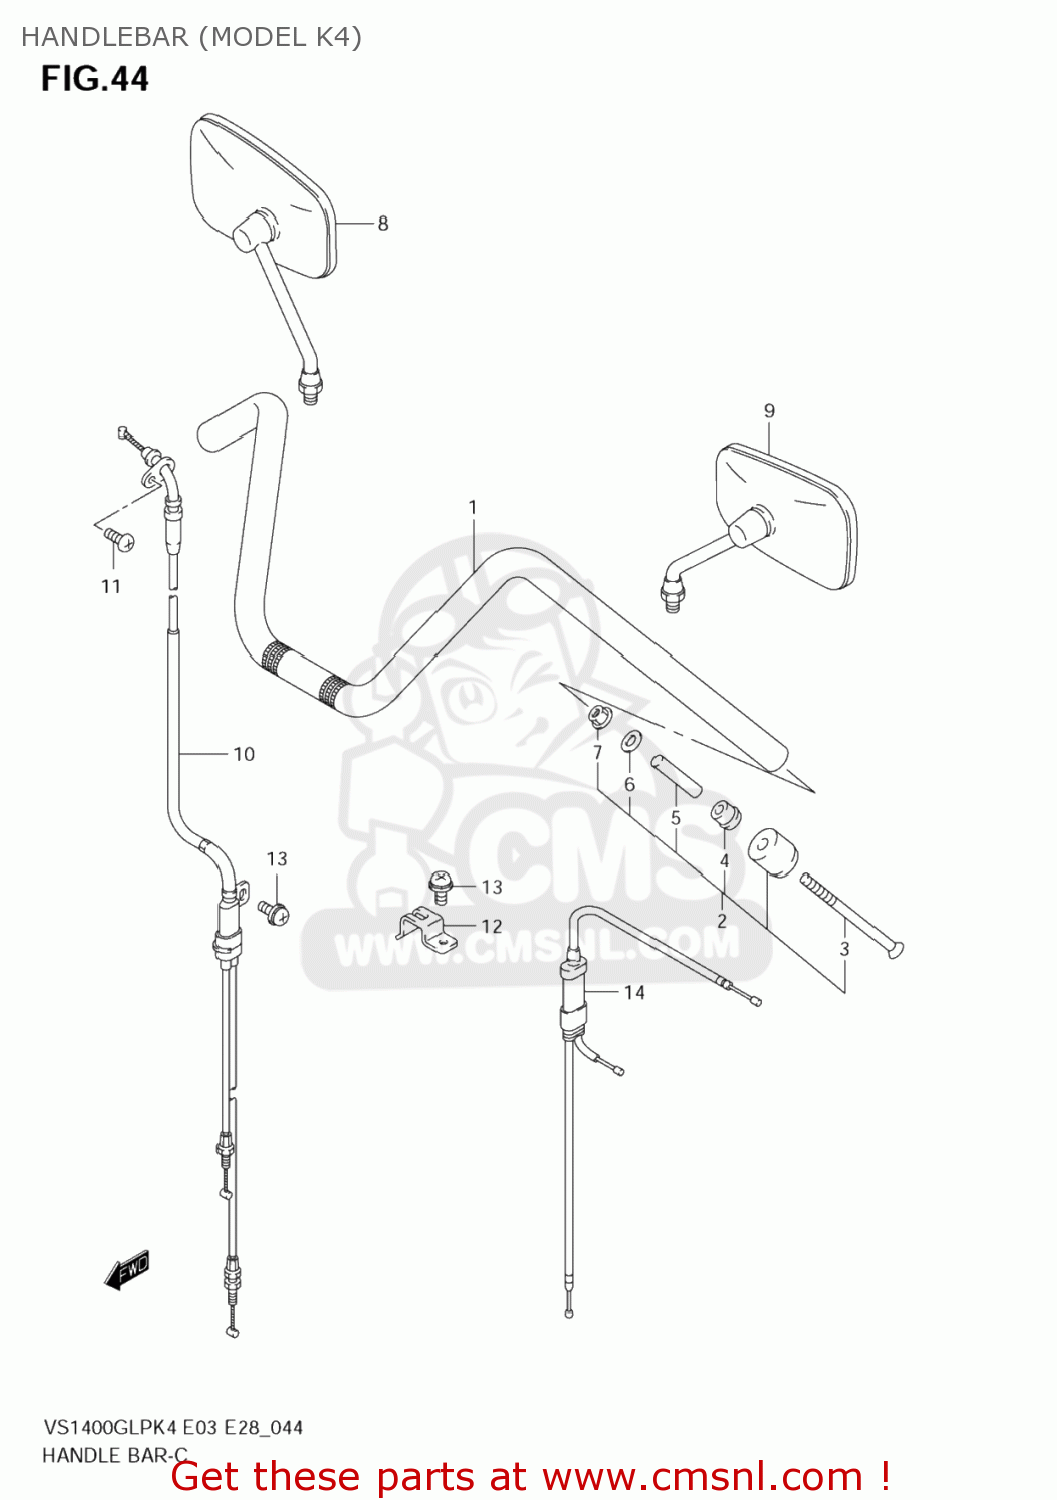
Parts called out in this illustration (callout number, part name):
1	HANDLEBAR
2	BALANCER SET,HANDLEBAR
3	SCREW(6X110)
4	EXPANDER,HANDLE BALANCER NO.2
5	SPACER,EXPANDER
6	WASHER(6.5X18X2)
7	NUT
8	MIRROR ASSY,RR VIEW,R
9	MIRROR ASSY,RR VIEW,L
10	CABLE ASSY,THROTTLE
11	SCREW
12	CLAMP,THROTTLE CABLE CONNECTOR
13	SCREW
14	CABLE ASSEMBLY,STARTER
